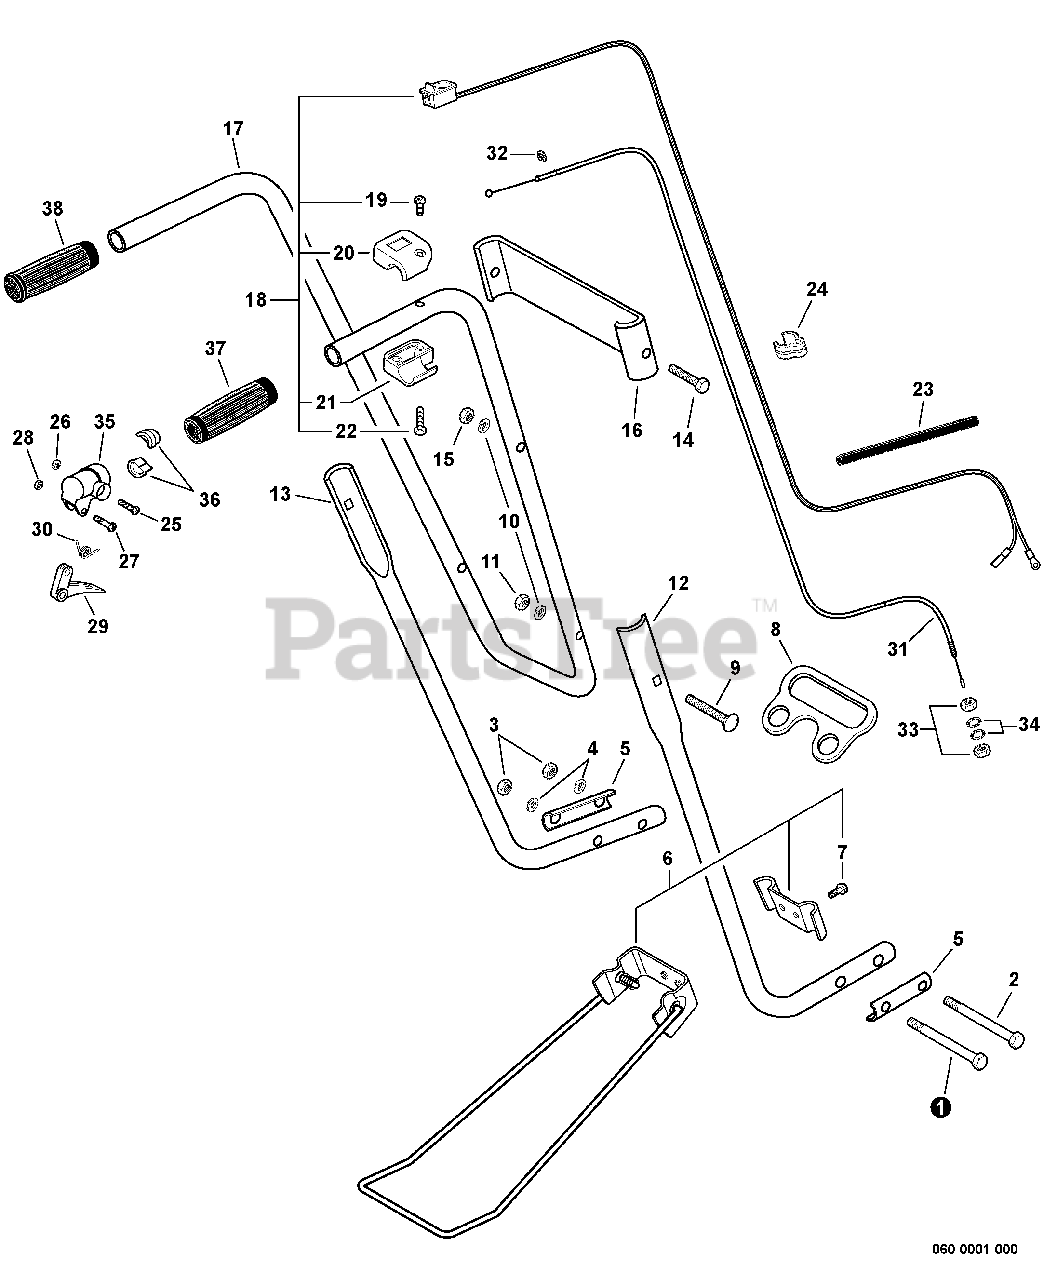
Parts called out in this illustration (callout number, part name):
1	BOLT - 1/4 X 3-1/4"
2	BOLT - 1/4 X 3"
3	LOCKNUT - 1/4"
4	LOCKWASHER
6	KICK STAND KIT
7	BOLT - 6X12
8	HANDLE, LIFTING
9	BOLT - 1/4 X 1-1/4"
10	LOCKWASHER
11	NUT - 1/4"
12	HANDLE, LOWER - RIGHT
13	HANDLE, LOWER - LEFT
14	BOLT - 1/4 X 1-1/4"
15	LOCKNUT - 1/4"
16	BRACKET, HANDLE
17	HANDLE - UPPER
18	IGNITION SWITCH KIT
19	SCREW - 5X10
20	CASE, SWITCH - UPPER
21	CASE, SWITCH - LOWER
22	SCREW - 3
23	TUBE - VINYL
25	SCREW - 5X25
26	LOCKNUT - 5
27	SCREW - 5X30
29	TRIGGER, THROTTLE
30	SPRING, TRIGGER
31	CABLE, THROTTLE
32	RING, RETAINING
34	LOCKWASHER - 6
35	BRACKET, TRIGGER
37	GRIP, HANDLE - RIGHT
38	GRIP, HANDLE - LEFT
